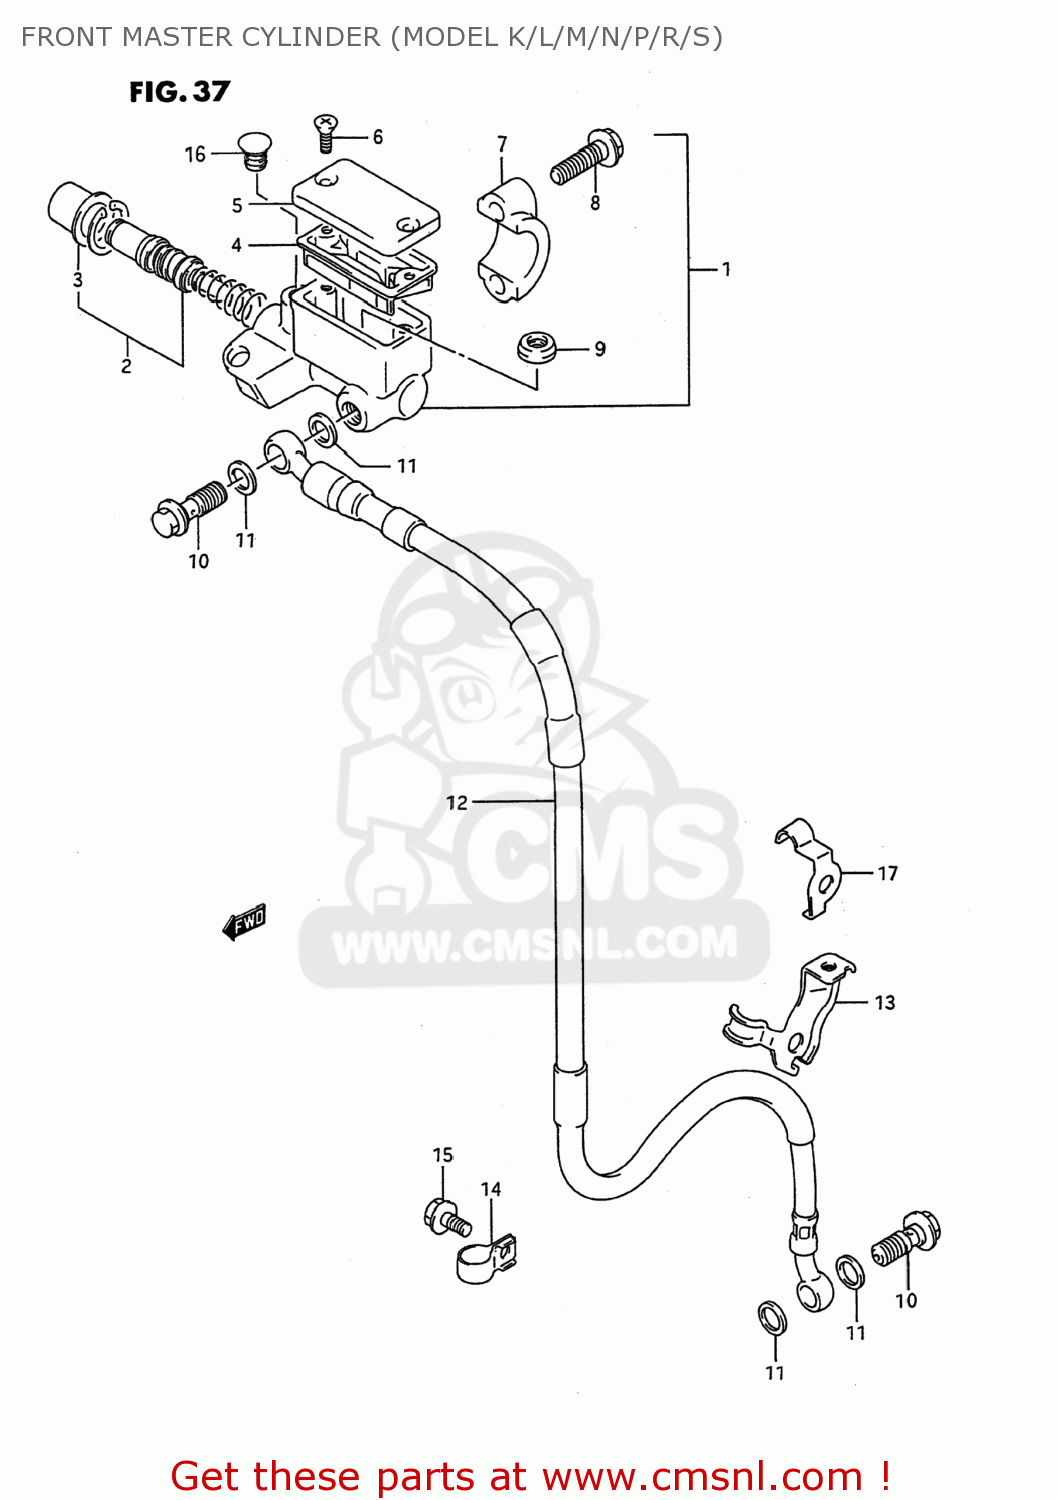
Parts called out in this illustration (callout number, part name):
1	CYLINDER ASSEMBLY,FRONT MASTER
2	PISTON & CUP SET
3	BOOT
4	DIAPHRAGM
5	CAP
6	SCREW
7	HOLDER
8	BOLT
9	SEPARATOR
10	BOLT UNION
11	WASHER(10X15X1.5)
12	HOSE,FRONT BRAKE
13	CLAMP,FRONT BRAKE HOSE
14	CLAMP,FR BRAKE HOSE NO.2
15	BOLT
16	CAP(OD:14)
17	CLAMP,FRONT BRAKE HOSE
